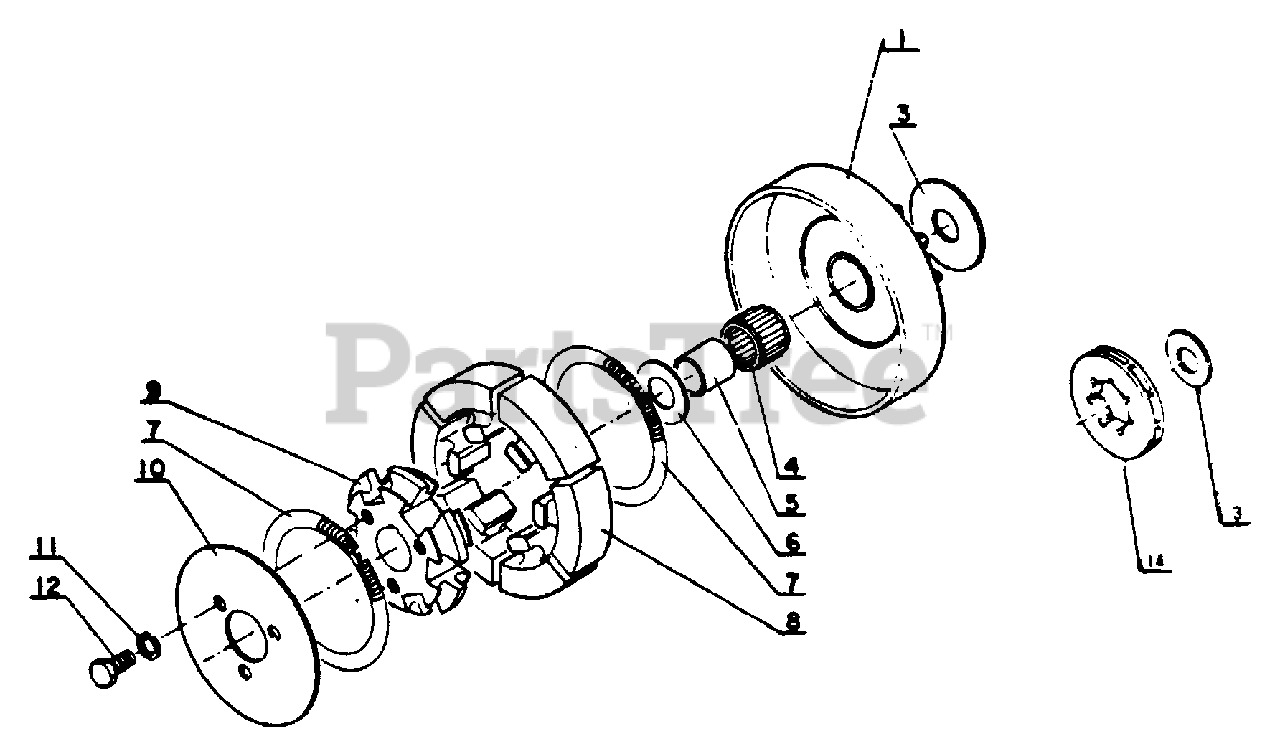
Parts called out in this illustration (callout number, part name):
1	DRUM, CLUTCH
3	WASHER, CLUTCH
4	BEARING, NEEDLE
6	WASHER, CLUTCH
7	SPRING, CLUTCH
8	SHOE, CLUTCH
9	HUB, CLUTCH
10	PLATE, CLUTCH
11	WASHER, SPRING 5
12	BOLT - 5×10
14	LIM
